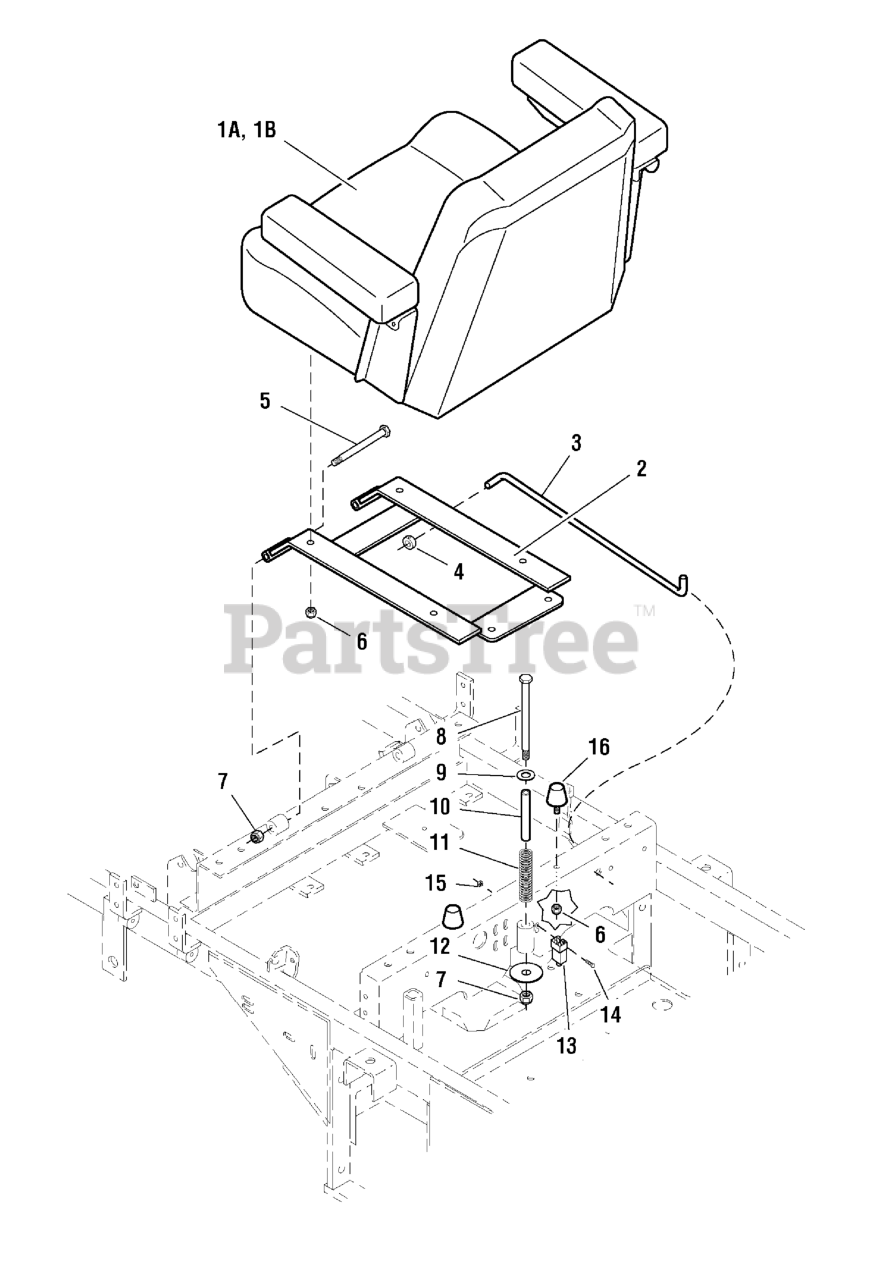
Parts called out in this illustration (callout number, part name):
1A	SEAT, GRAY, NO LOGO, CMPT
1A	SEAT BOTTOM (EVC 907)
1A	CUSHION, Back, Gray
1A	ARM REST, Black
1A	SEAT ADJUSTER RAILS (set of 2)
1B	SEAT, Deluxe, Gray, Complete
1B	SEAT Bottom Cover
1B	SEAT Back Cover
1B	ARM REST SET
1B	ARM REST PADS
1B	SEAT ADJUSTER RAILS (set of 2)
2	WELD, SEAT MOUNT
3	SEAT STOP ROD
4	COLLAR, 5/16" Set
5	BOLT, 3/8-16 X 4" GD5 CZ
6	NUT, 5/16-18 Hex Nylon Lock
7	NUT, 3/8-16 HEX NYLON LOCK
8	BOLT, 3/8-16 X 6" GD5 CZ
9	WASHER, 3/8 SAE
10	SPACER, .38 X .50 X 5.06
11	SPRING, Compression
12	WASHER, 3/8 x 2
13	SWITCH (see electrical group)
14	SCREW, #10-24 X 1 RS, CZ
15	NUT, #10-24 Hex
16	RUBBER BUMPER
17	SPRING, EXTENSION, SEAT ADJUSTMENT (YEL OR BLK)
